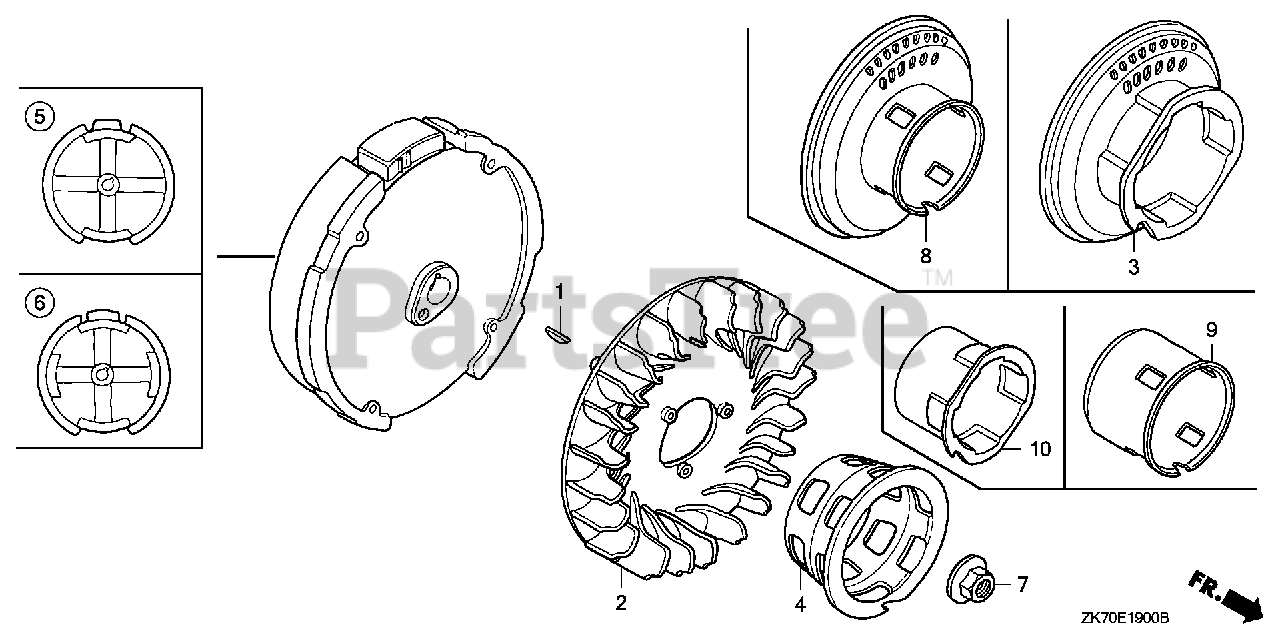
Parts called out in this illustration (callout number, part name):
1	KEY, SPECIAL WOODRUFF (25X18)
2	FAN, COOLING
5	FLYWHEEL
7	NUT, SPECIAL (14MM)
9	PULLEY, STARTER
10	PULLEY, STARTER
